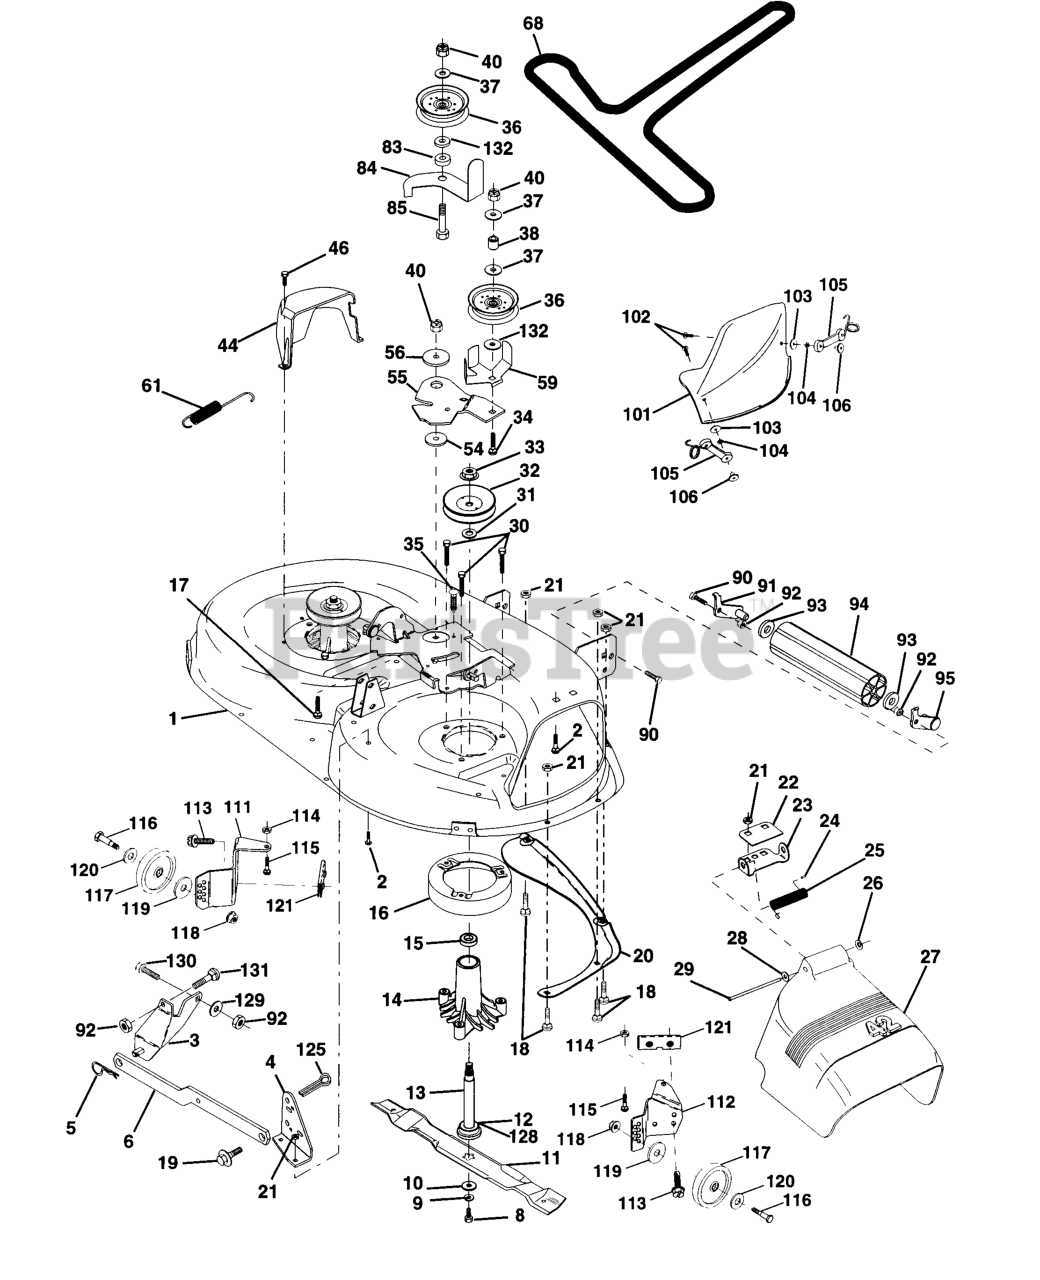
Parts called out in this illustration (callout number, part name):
1	DECK 42"
2	RP BOLT 5/16-18 X3/4 ZN/YEL GR
3	BRKT ASM SWAY BAR
4	BRKT DECK SW BAR
5	RETAINER-SPRNG RB
6	REAR SUSP ARM
8	BLADE BOLT
9	LOCKWASHER
10	WASHER.BLADE
11	BLADE.42".MULCH
12	BEARING.BALL.#6204.(MANDREL)
13	SHAFT ASM VENT
14	HOUSING.MANDREL.VENTED (MACHD)
16	STRIPPER
17	BOLT CARRIAGE
18	BOLT
19	BOLT SHD 5/16-18
20	BAFFLE
21	LOCKNUT
22	STIFFENER BRACKET
23	DEFLECTOR BRACKET
24	CAP-SLEEVE LT
25	SPRING TORSION
26	NUT PUSH M
27	SHIELD.DEFLECTOR.MOWER.42".BLK
28	Washer 11/32 X 5/8 X 16 Ga
29	ROD.HINGE
30	SCREW
31	WASHER
32	PULLEY/MANDREL
33	NUT
35	FASTENER.XMAS.TREE
36	FLAT IDLER PULLEY
37	WASHER
38	IDLER SPRING SPACER
44	GUARD MANDREL LH BLACK
46	SCREW.1/4-20X5/8
54	HARDENED WASHER
55	IDLER ARM
56	SPACER RETAINER
59	GUARD, BELT
61	SPRING EXTENSION
68	V-BELT TRIPATH
84	KEEPER.BELT.IDLER
85	BOLT
90	BOLT
91	BRACKET LH (A)
92	NUT
93	Washer 17/32 X 7/8 X 16 Ga
94	NOSE ROLLER
95	BRACKET RH (B)
101	COVER MULCH 42"
102	SCREW
104	LOCKWASHER #10
105	LATCH ASSEMBLY
106	WELDNUT
111	BRACKET WHEEL GAUGE LH 42" DK
112	BRACKET WHEEL GAUGE RH 42" DK
113	SCREW.THDROL.5/16-18X3/4.TTY
114	NUT
115	BOLT.CARR.5/16-18X1/2
116	BOLT M
117	WHEEL.GAUGE.BLK.4.93
118	LOCKNUT
119	WASHER.5/16.FLAT.STE.STD.
120	Washer 17/32 x 15/16 x 12 Ga.
121	BRACKET.EXTRUDED.GAGE.WHEEL
125	Cotter Pin
128	WASHER FELT
129	WASHER
130	BOLT
131	BOLT D
